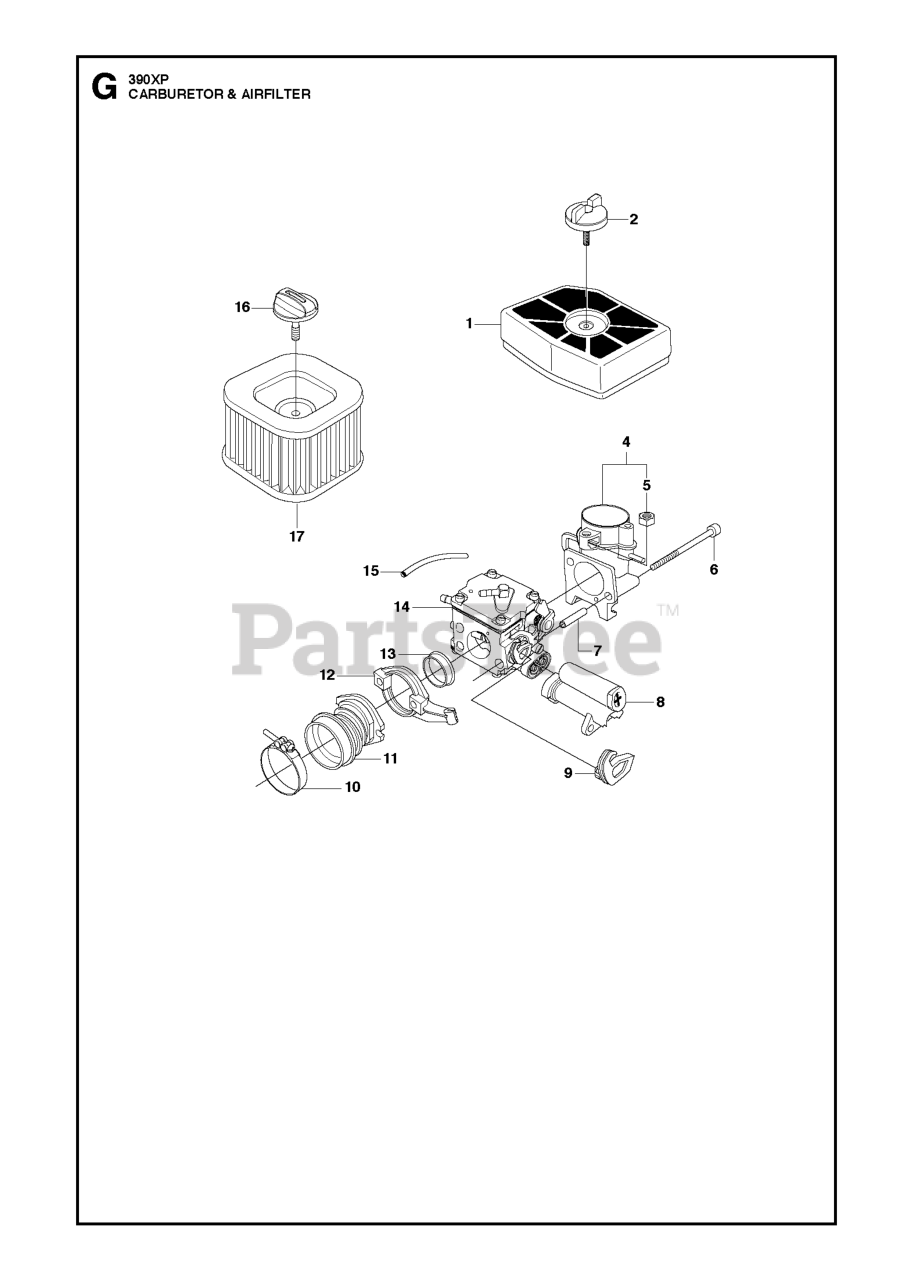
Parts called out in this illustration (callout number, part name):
1	AIR FILTER
4	FILTER HOLDER
8	GUIDE BUSHING
10	CLAMP
11	PIPE
11	RP INTAKE PIPE
14	CARBURETOR
16	HANDLE AIR FILTER COVER
17	AIR FILTER - FELT
